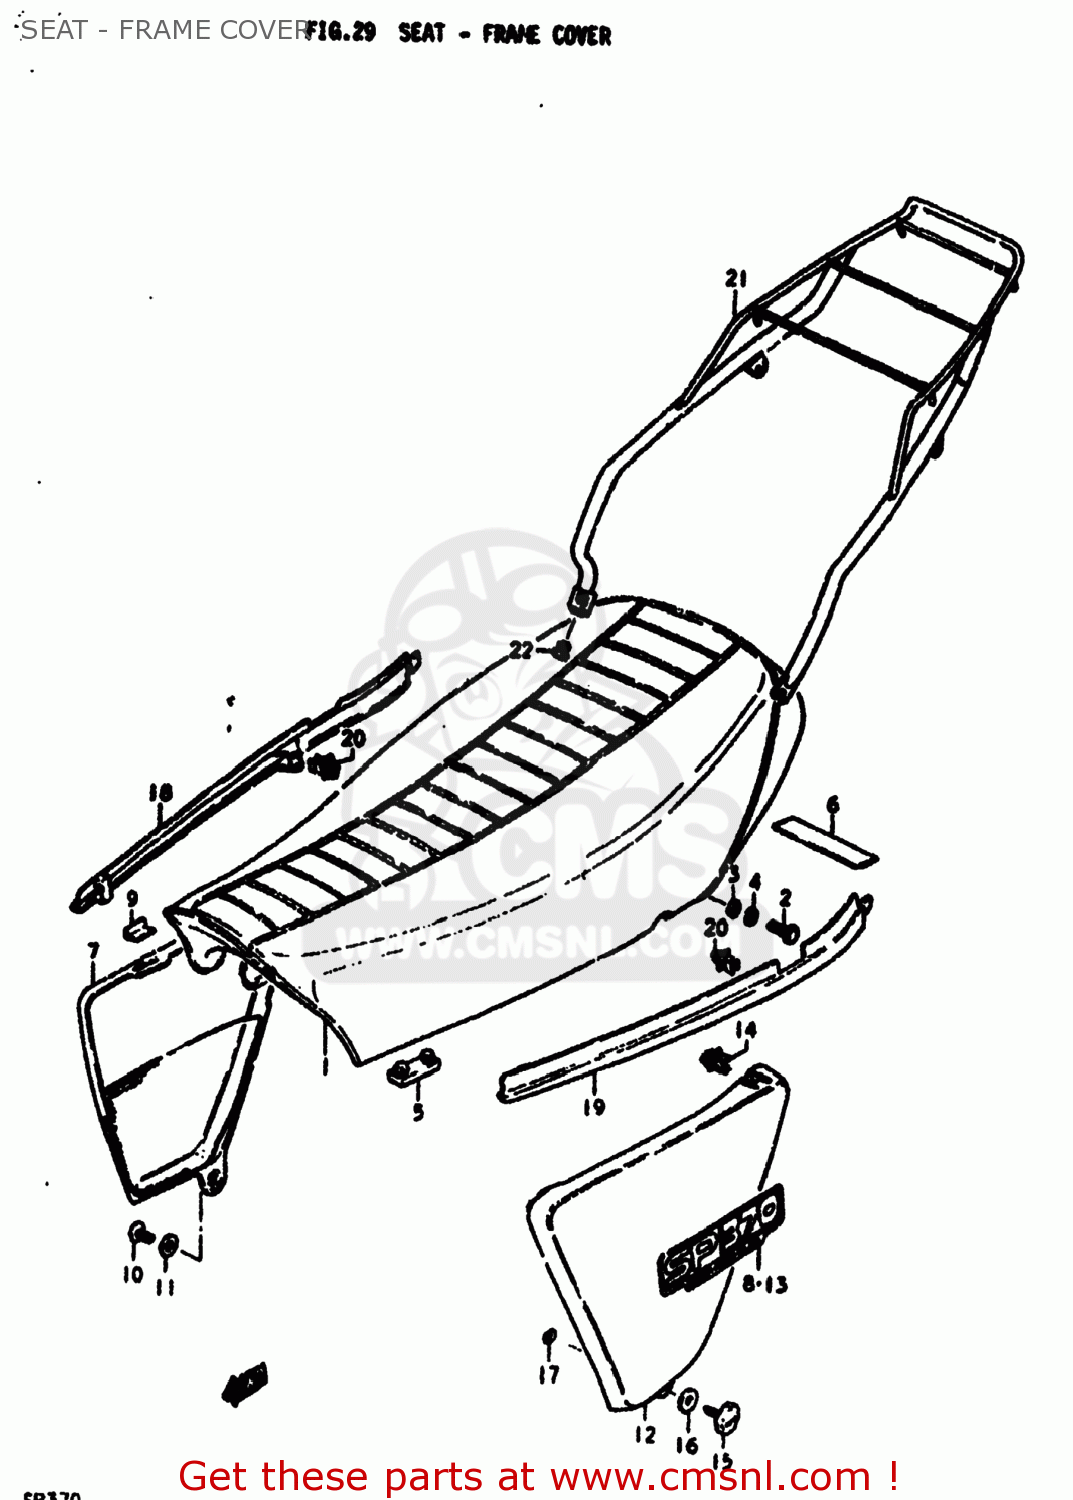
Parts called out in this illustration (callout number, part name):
1	SEAT ASSEMBLY
2	BOLT
3	WASHER
4	LOCK WASHER
5	CUSHION
6	CUSHION,FRAME
7	COVER,FRAME,RIGHT
8	EMBLEM,FRAME COVER
9	CUSHION,FRAME COVER
10	SCREW
11	WASHER
12	COVER,FRAME,LEFT
13	EMBLEM,FRAME COVER
14	CLAMP
15	KNOB,FRAME COVER,R
16	WASHER
17	NUT
18	COVER,FRAME
19	COVER,SEAT,LOWER,LEFT
20	CLAMP
21	CARRIER
22	CAP(OD:17)
